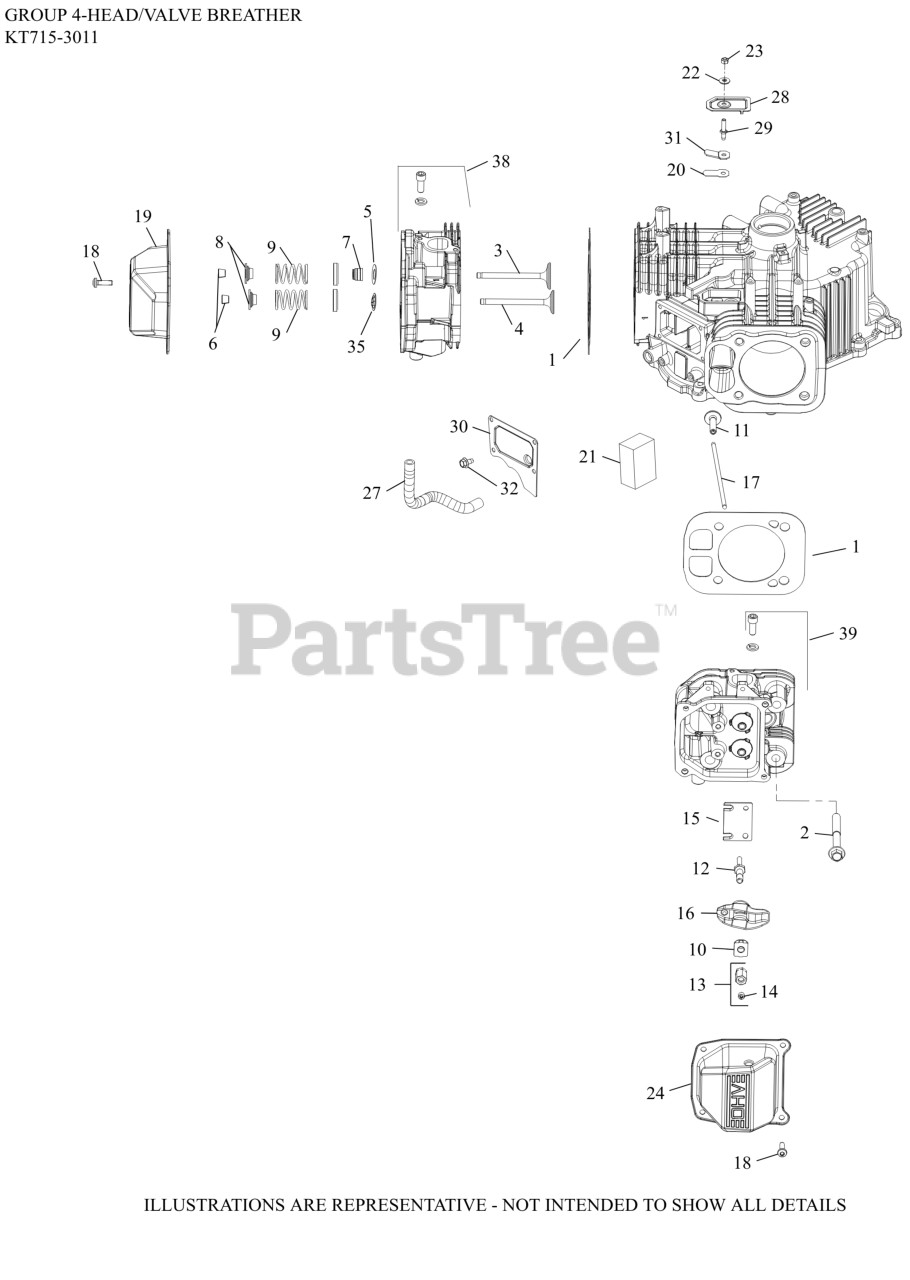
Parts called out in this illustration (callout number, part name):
1	KIT, CYLINDER HEAD GASKET
2	SCREW, FLG M10X1.5X90
3	VALVE, INTAKE
3	VALVE, INTAKE (.25) - (#2401702S)
4	VALVE, EXHAUST
4	VALVE, EXHAUST (.25)
5	SPACER (.010")
6	KIT, RETAINER
7	SEAL, VALVE BAND
8	CAP, VALVE SPRING
9	SPRING VALVE
10	PIVOT, ROCKER ARM
12	STUD, ROCKER
13	HEX NUT ASSEMBLY
14	SCREW, SET
15	PLATE, GUIDE
16	ARM, ROCKER
17	ROD, PUSH
18	SCREW, PAN HEAD
19	COVER, ROCKER STAMPED STEEL
20	REED, BREATHER
21	FILTER, BREATHER
22	WASHER, SEALING
23	NUT, LOCK M5X.8
24	COVER, ROCKER STAMPED STEEL
25	HEAD, ASSY CYL (#1)-USE 32 755 29-S
27	HOSE, BREATHER
28	COVER, BREATHER REED
30	COVER, BREATHER MEDIA
31	RETAINER, REED
32	SCREW, THREAD FORMING
35	RETAINER, VALVE GUIDE (KM)
38	KIT, #1 HEAD AND HARDWARE-(#3275539S)
39	KIT, #2 HEAD AND HARDWARE-(#3275540S)
